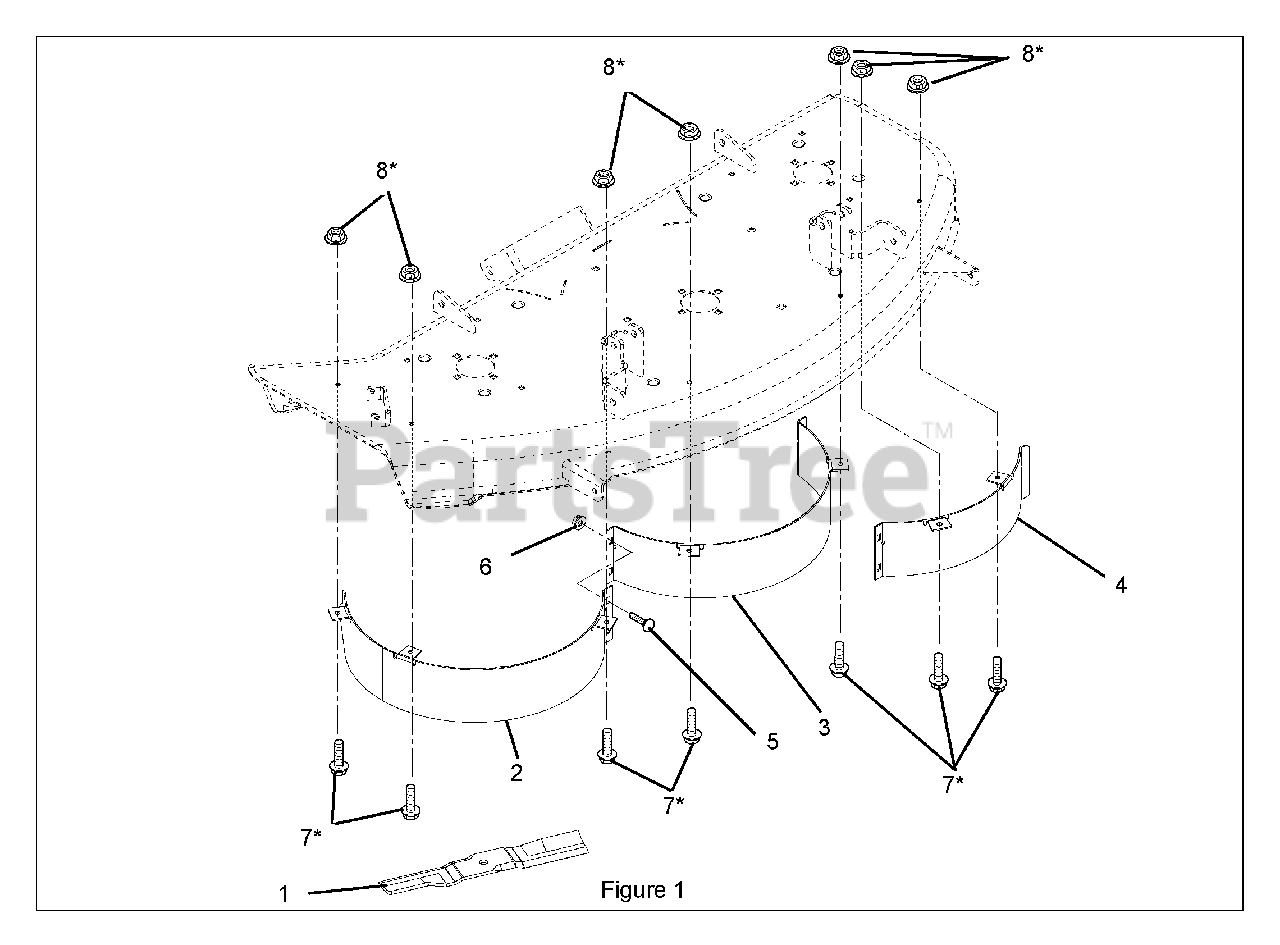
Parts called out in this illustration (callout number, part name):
1	Mulching Blade
2	Right Mulch Baffle
3	Center Mulch Baffle
4	Left Mulch Baffle
5	5/16" Round Head Square Neck Bolt
6	5/16" Top Lock Flange Nut
7	5/16" x 3/4" Hex Bolt
8	5/16" Spinlock Flange Nut
